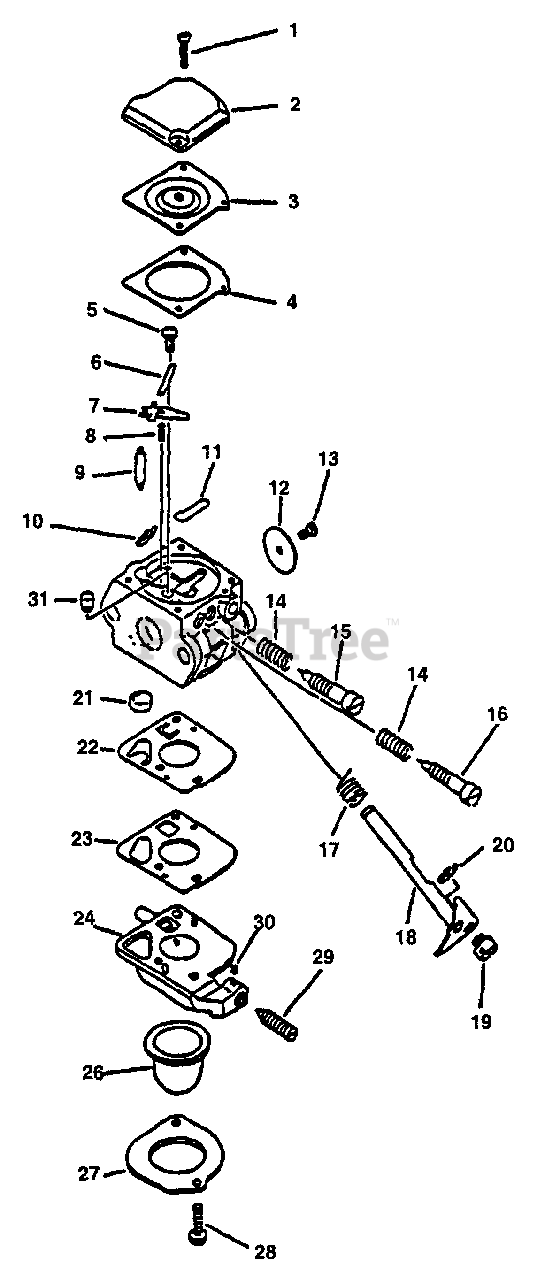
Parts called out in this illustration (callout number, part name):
2	COVER, METERING
3	DIAPHRAGM
4	GASKET, METERING
5	SCREW, METERING LEVER PIN
6	PIN
7	LEVER, METERING
8	SPRING
9	VALVE, NEEDLE
10	RING, RETAINING
11	PLUG, WELCH
12	VALVE, THROTTLE
15	NEEDLE - LOW SPEED
16	NEEDLE - HIGH SPEED
17	SPRING, RETURN
18	SHAFT, THROTTLE
19	RING, RETAINING
21	STRAINER
22	DIAPHRAGM, PURGE
23	GASKET, PURGE
24	BASE, PURGE
26	BULB, PURGE
27	RETAINER, PURGE BULB
28	SCREW, RETAINER
29	SCREW, IDLE ADJUST
30	PIECE, FRICTION
31	NOZZLE, CHECK VALVE
